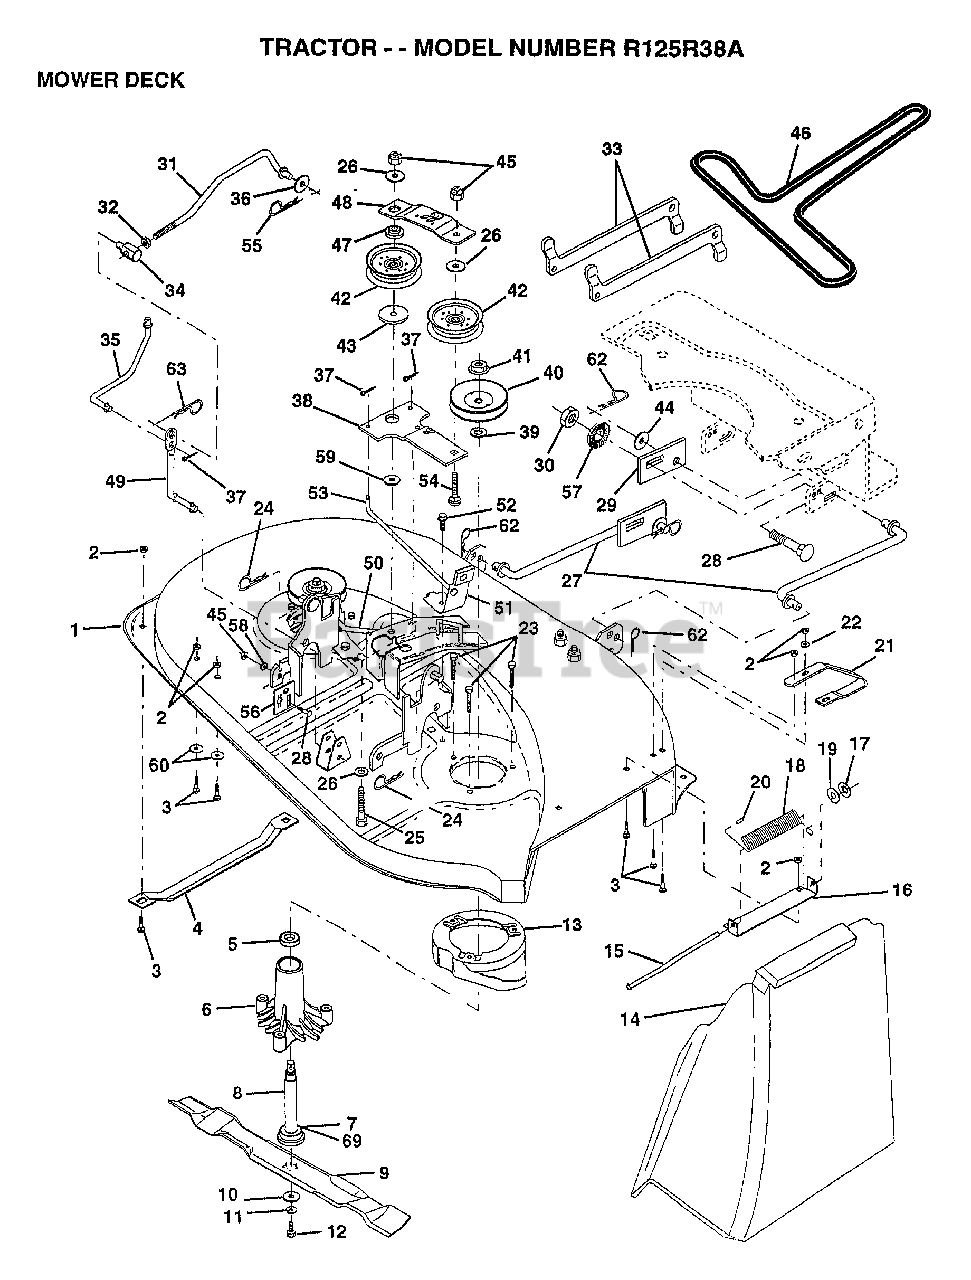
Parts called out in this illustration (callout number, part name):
1	MOWER.WELD.LR.38
3	BOLT
4	RUNNER-LH M
5	BEARING
6	HSG ASM MANDREL
7	BEARING.BALL
9	"BLADE.38"" HIPERF"
10	WASHER.HARD.BLADE
12	BLADE BOLT
13	STRIPPER RND MWR
14	DEFLECTOR-SHLD T
15	ROD-HINGE T
16	BRKT DEFLECTOR
17	NUT PUSH M
18	SPRING TORSION
19	WASHER
20	CAP-SLEEVE LT
21	RUNNER RH
22	WASHER M
25	BOLT
26	WASHER GT
27	"LINK LIFT 38"""
29	PLATE SLIDE LINK
30	NUT
31	ROD.CLUTCH.PRIM
32	NUT
33	SUSP ARM REAR
34	TRUNION ADJ
35	CLUTCH ROD SEC
36	WASHER
38	IDLER ARM ASSY
39	WASHER
40	PULLEY.MANDREL.38
42	PULLEY IDLER
43	SPACER RETAINER
44	WASHER 1/2X1 1/4
46	BELT.V.T-PATH
47	RETAINER SPACER
48	IDLER ARM STIFF
49	PIVOT ROD
50	BRAKE ROD LH
51	BRAKE ASM
52	SCREW
53	BRAKE ROD RH
54	BOLT
55	SPRING.RETAINER
56	PLATE ADJ LINK LH
57	WASHER.SERRATED.
58	WASHER T
59	HARDENED WASHER
60	WASHER.34X.68X16
62	RETAINER.SPRING
63	RETAINER M
69	WASHER.FELT.
